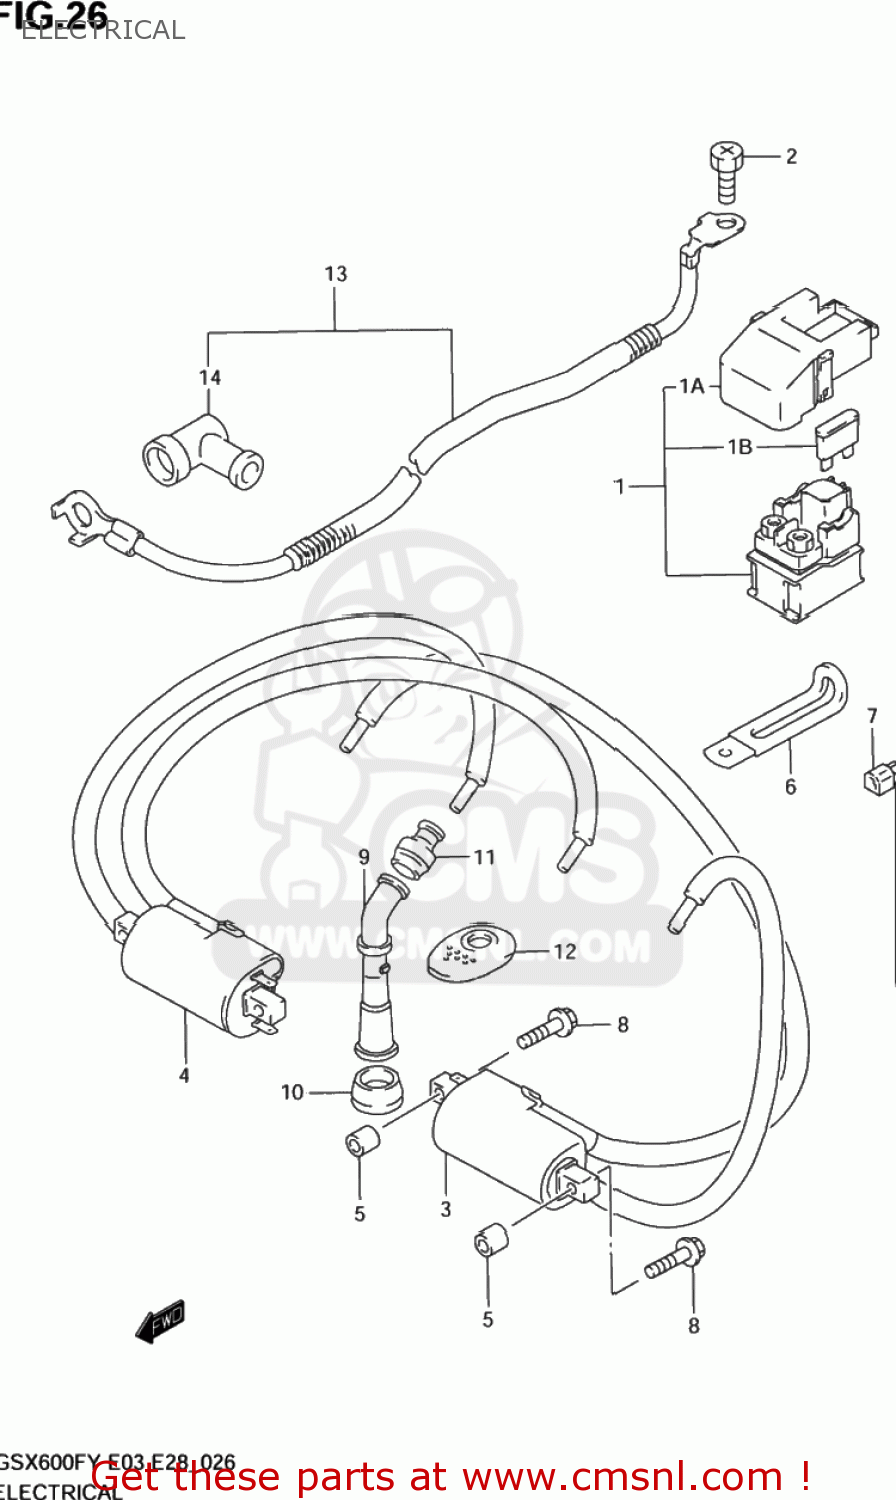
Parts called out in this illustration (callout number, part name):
1	RELAY ASSY,STARTING MOTOR
1A	COVER,RELAY ASSEMBLY
1B	FUSE(30A)
2	SCREW(6X8)
3	COIL ASSY,IGNITION
4	COIL ASSY,IGNITION
5	SPACER(6.2X12X14)
6	CLAMP(L:65)
7	CLAMP(L:165)
8	BOLT (6X45)
9	CAP,SPARK PLUG
10	SEAL,SPARK PLUG CAP
11	SEAL,HIGH TENSION CORD
12	COVER,SPARK PLUG CAP
13	WIRE,BATTERY MINUS
14	CAP,STARTER MOTOR LEAD
